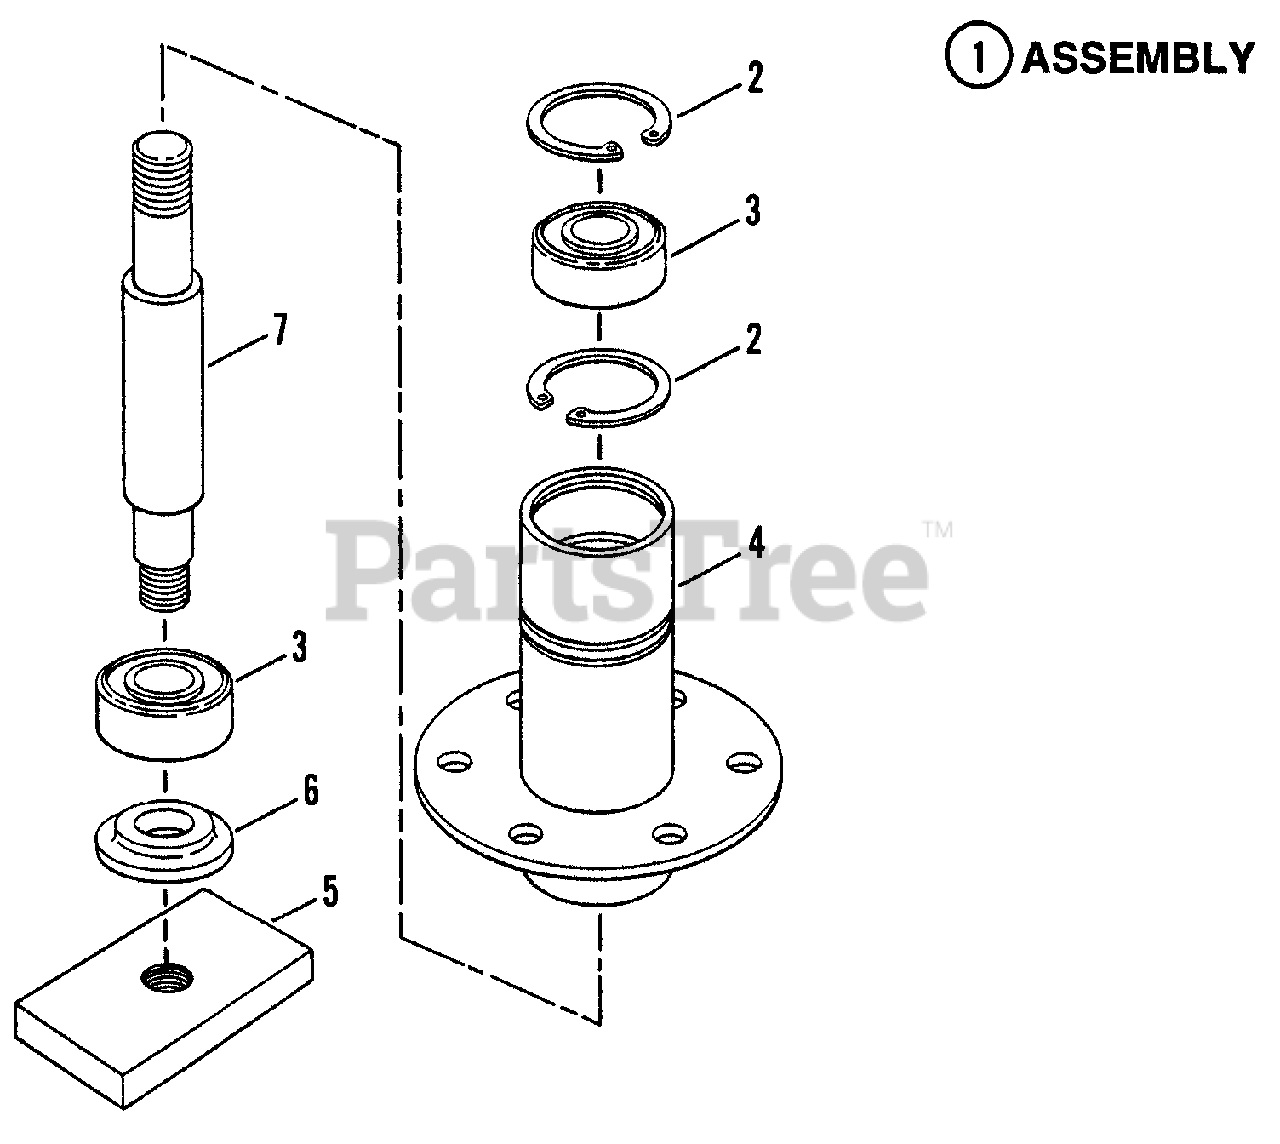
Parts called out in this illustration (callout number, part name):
1	ASSEMBLY, Spindle Housing, 42" (LH) Cutting Deck
1	ASSEMBLY, Spindle Housing, 42" (RH) Cutting Deck
2	RING, Retaining
3	BEARING, Spindle
4	HOUSING, Spindle, (4.35" Tall)
4	HOUSING, Spindle, RH (5" Tall)
5	HOLDER, Blade
6	WASHER, Spindle
7	SPINDLE, LH (5.75" Long)
7	SPINDLE, RH (5.1" Long)
